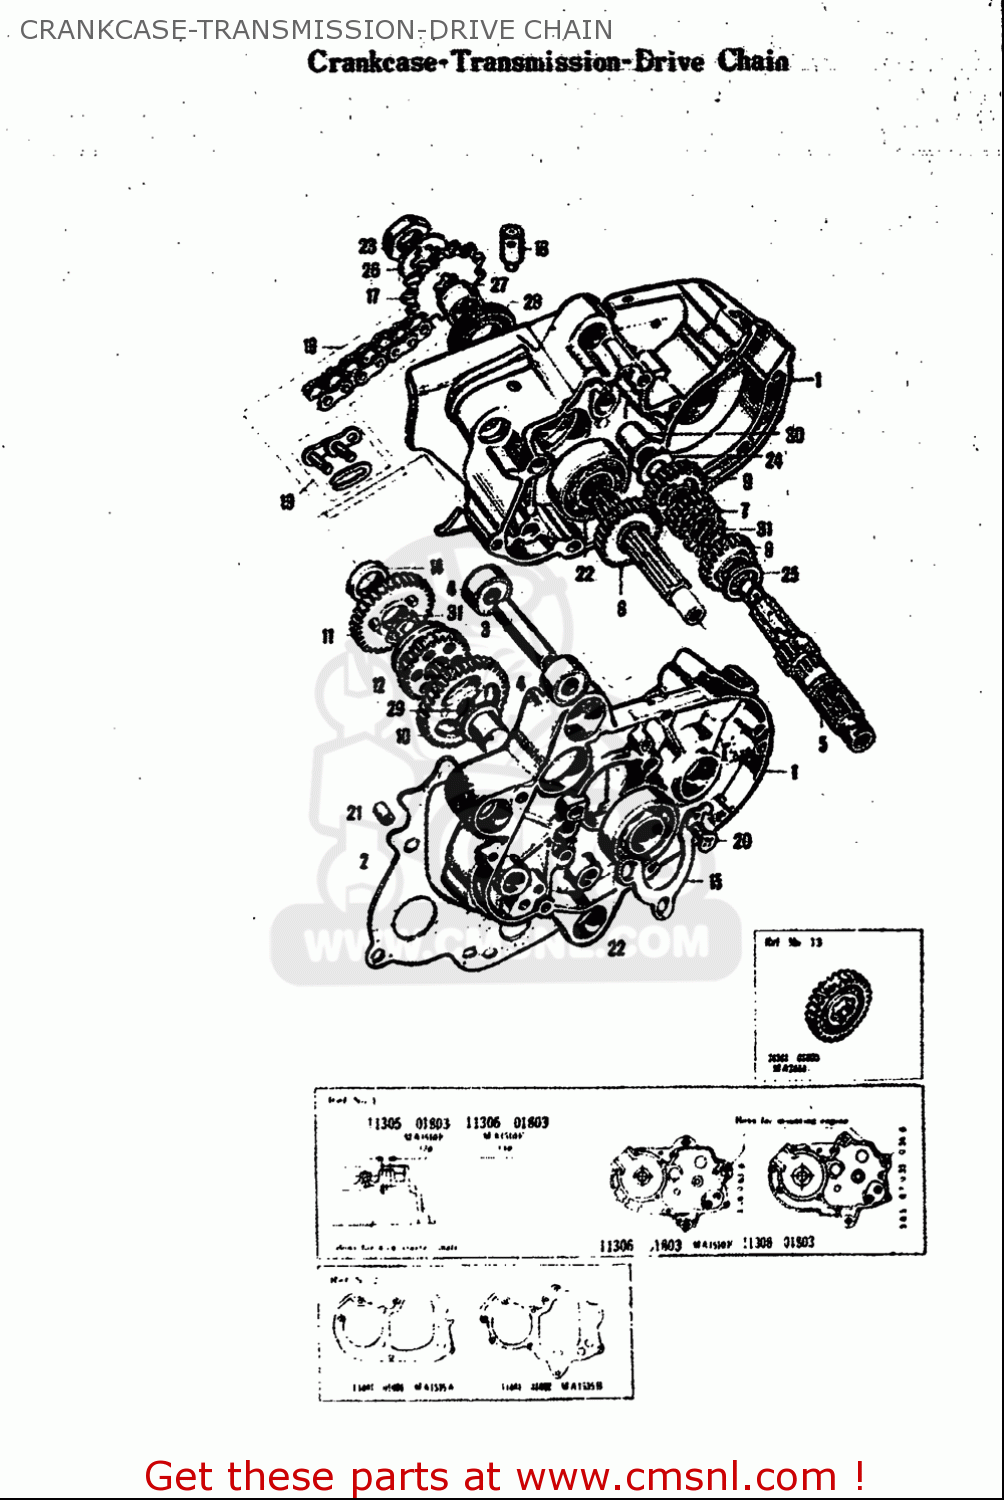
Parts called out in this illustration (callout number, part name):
16	PLUG,T/M BREATHER
17	SPROCKET,ENGINE
19	JOINT
21	PIN
22	BEARING
23	NUT
24	TOP PINION THRUST WASHER (M12MARK2,M15D,M12 OD=22(0.(0.43) T=1.2
26	WASHER,LOCK
27	SPACER(17X21X13)
28	SEAL,OIL(21X40X7)
